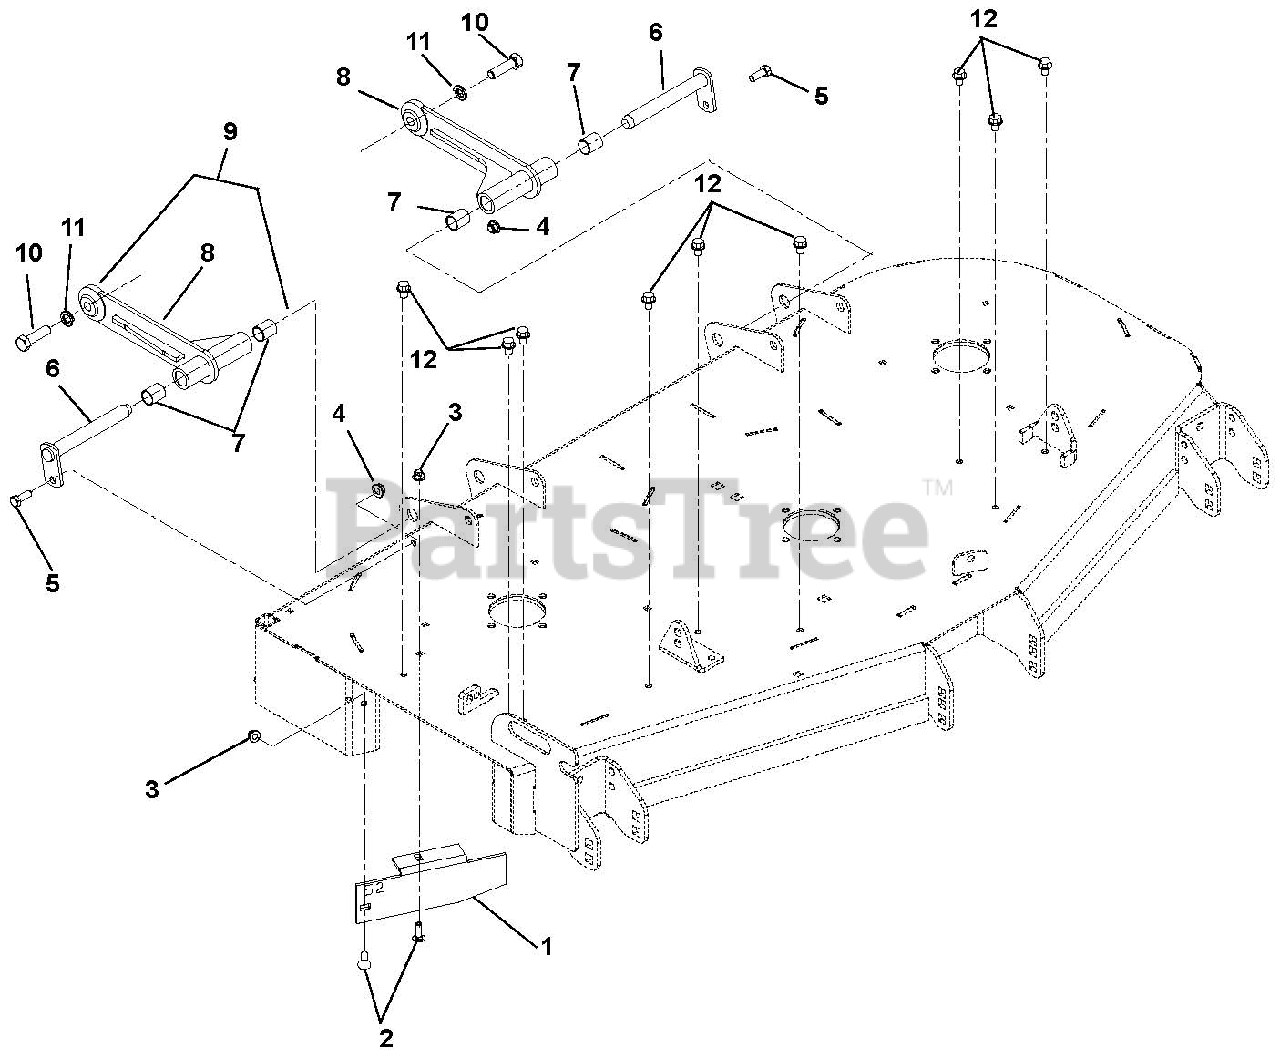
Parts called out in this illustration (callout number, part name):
1	Discharge Baffle, 44"
2	Bolt, Round Head Square Neck .31-18 x 1.00 Grade 5
3	Nut, .31-18 Nyloc Flange
4	Nut, .38-16 Nyloc Flange
5	Bolt, Hex .38-16 x 1.00 Grade 5
6	Weldment, Mower Mounting Pin
7	Bearing, .75 x .875 x 1.00
8	Deck Pusher Arm Weldment
9	Assembly, Mower Mount Arm
10	Bolt, Hex .50-13 x 1.75 Grade 5
11	Washer, Locking .50 x .125 Regular
12	Screw, Tapping .38-16 x .50 Hex Washer Head
